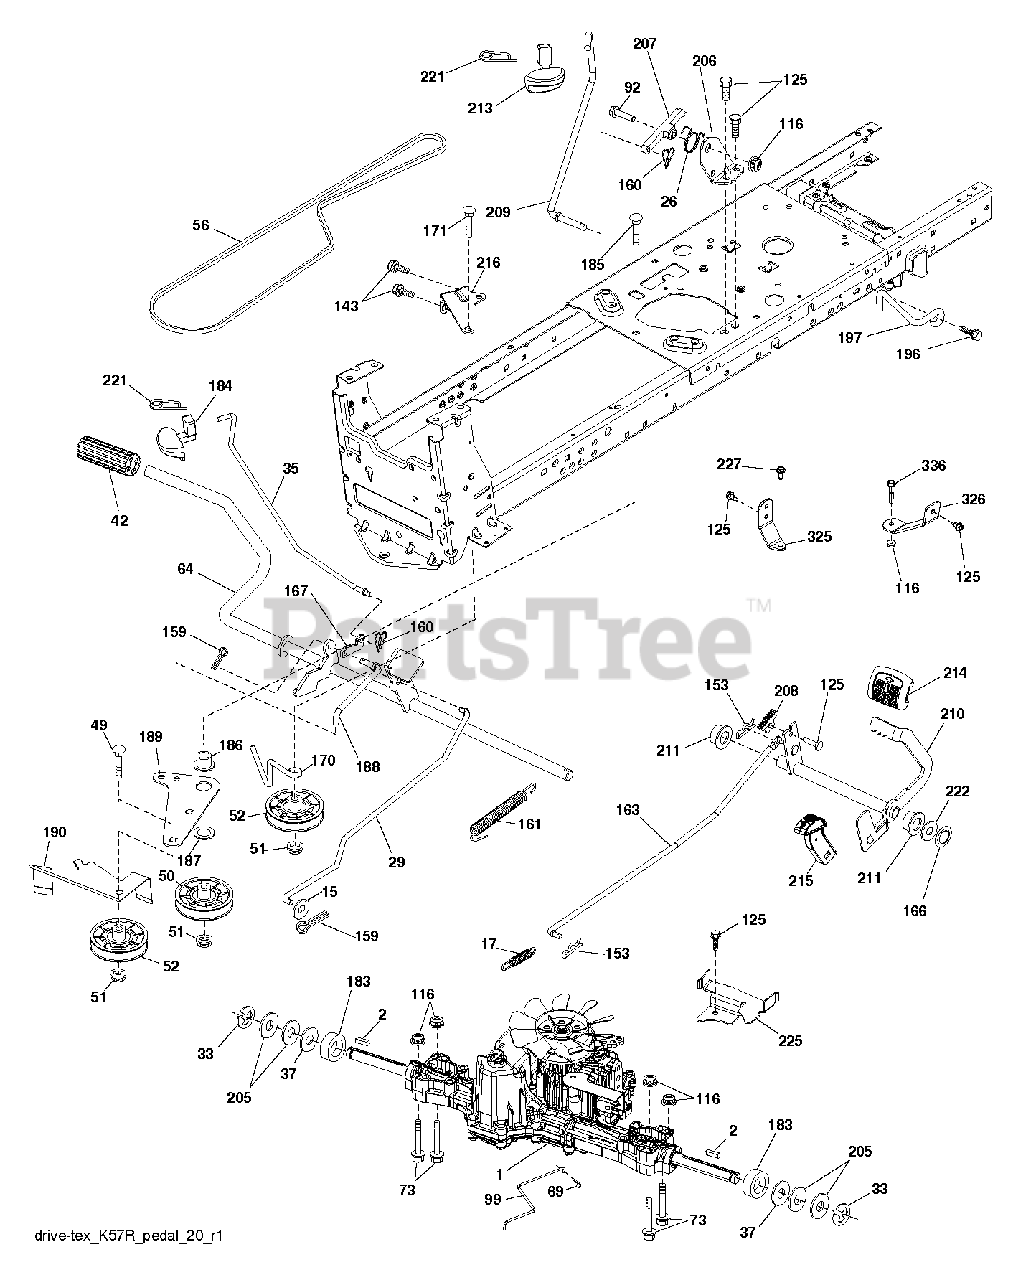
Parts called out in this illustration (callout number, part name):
2	SQUARE KEY
15	WASHER
17	SPRING.BRAKE.K46.GREEN
26	SPRING.RETURN.CRUISE
29	ROD.BRAKE.K46
35	ROD .BRAKE. PARKING. GT. HUSQ.
37	WASHER.HARDENED
42	PEDAL COVER T
50	IDLER.FLAT.910.OFFSET
51	NUT LOCK FLG 3/8-16 UNC
52	IDLER.V-GROOVE.910.OFFSET
56	V-BELT.MOWER.92.40.42/K46
64	SHAFT.ASM.PEDAL.BRK.CNTR
69	HAIRPIN.SOFT.ZINC.059X1.125
92	BOLT
99	ARM.PIVOTING.TCRD.GEN2.5.BAGGE
116	NUT LOCK HEX FLANGE 5/16-18
125	SCREW
143	SCREW LT
153	RETAINER M
159	COTTER PIN
160	RETAINER CLIP
161	SPRING, RETURN LT
163	ROD.CONTROL.K57R.K46
166	NUT.PUSH.625
167	LATCH.BRAKE.SPRING
170	KEEPER.V-IDLER.CENTER.
183	SPACER AXLE
184	HANDLE.PARKING.BRAKE.H (BLK)
186	SPACER.RETAINER
187	WASHER 12/32X2X10GA
188	LINK.CLUTCH.GROUND DRIVE.LONG
189	BELLCRANK.GROUND.DRIVE.TEX.
190	KEEPER.BELLCRANK.DRIVE
196	SCREW 3/8-16X1
197	CLUTCH.ANTIROTATION.WIREFORM.
206	BRACKET.MOUNT.CRUISE.LATCH
207	LATCH.CONTROL.CRUISE.TEX
208	GEAR.SECTOR.CONTROL.CR
209	ROD.CONTROL.CRUISE.GT.
210	ROCKER.ASM.PEDAL.CONTR
211	BEARING.NYLON
213	KNOB.CONTROL.CRUSIE.HU
214	PEDAL.FORWARD.PAD.TEX
215	PEDAL.COVER.REVERSE.CRD.X428BK
216	BRACKET.PULLEY.IDLER.W/TEX
221	RETAINER.SPRING.CLIP.H
222	WASHER 21/32 X 1-1/4 X 10 GA.
225	KEEPER.BELT.TRANSAXLE.K46
227	SCREW
325	BRACKET.TRQ.STP.46.20".TIRE.LH
326	BRCKT.PNT.TRQ.STP.46.20TIRE.RH
336	BOLT.5/16-18X1-3/4.FLANGED.HEX
